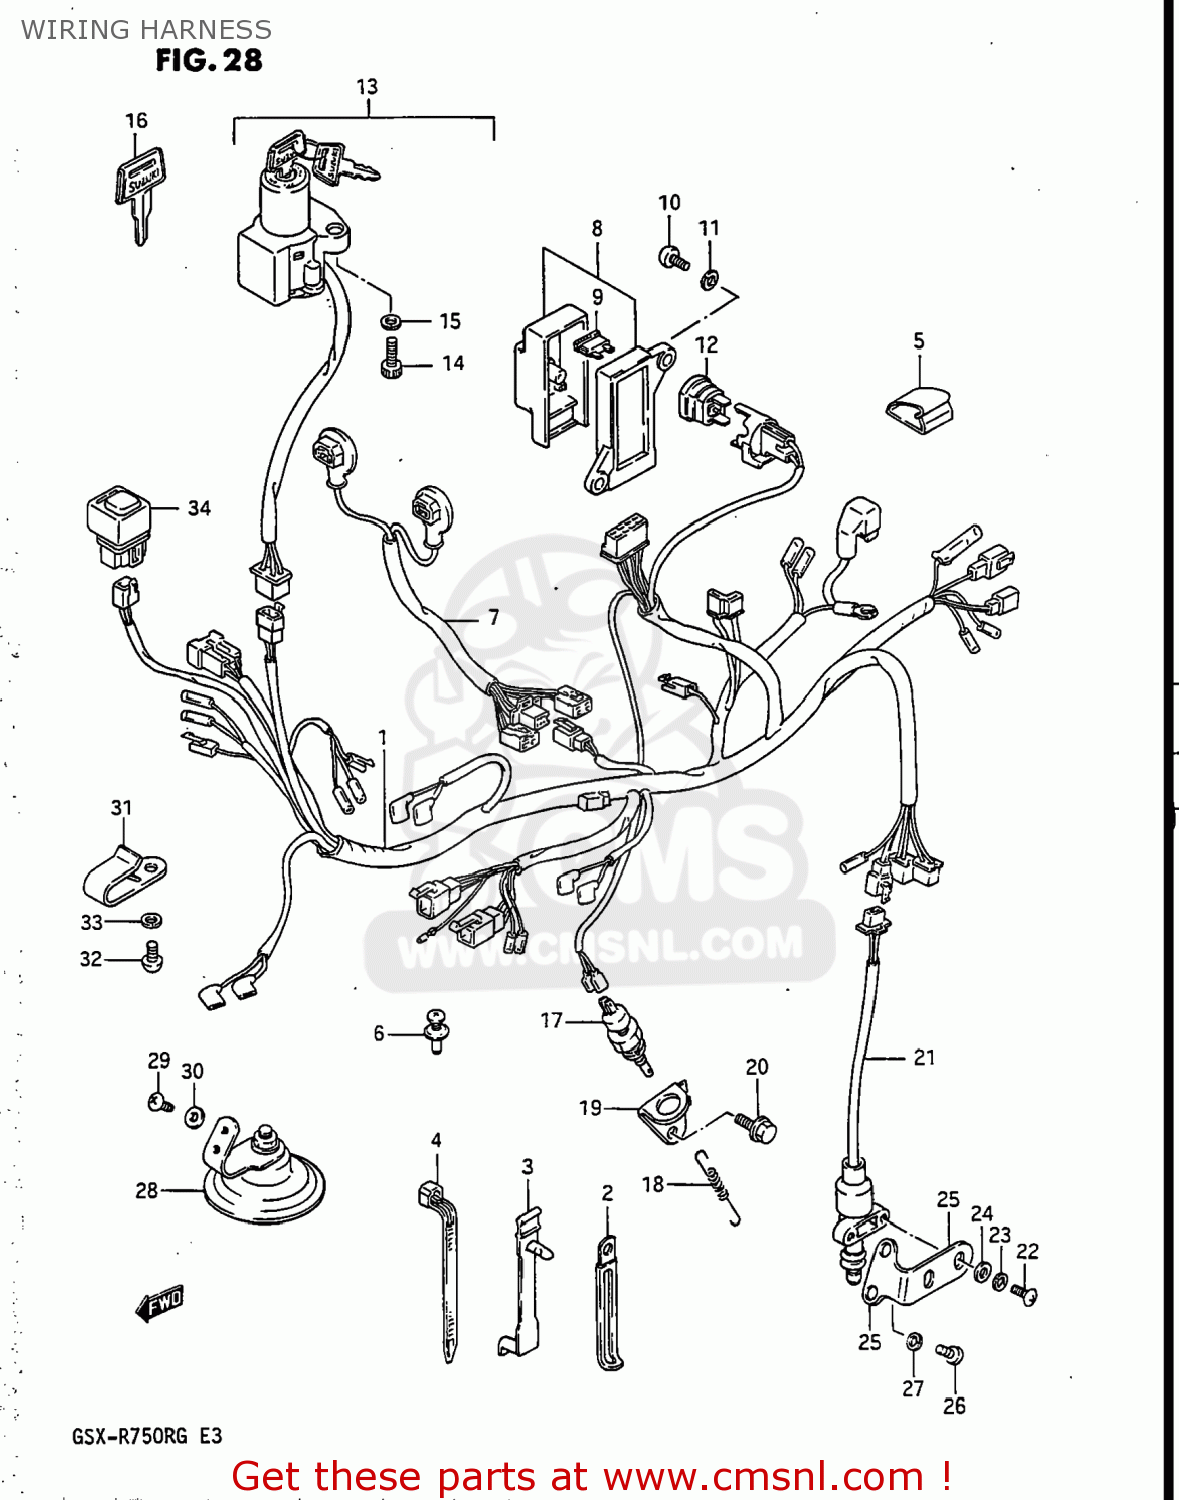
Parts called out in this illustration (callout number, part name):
1	HARNESS,WIRING
2	CLAMP
3	CLAMP(L:55)
4	CLAMP
5	CLIP
6	CLIP
7	WIRE
8	BOX ASSEMBLY,FUSE
9	FUSE(10A)
10	SCREW 6X12
11	WASHER
12	BREAKER ASSY,CIRCUT
13	SWITCH ASSY,IGNITION
14	BOLT
15	WASHER,LOCK
16	KEY,BLANK
17	SWITCH ASSY,STOP LAMP
18	SPRING
19	BRACKET,STOP LAMP SWITCH
20	BOLT (6X20)
21	SWITCH ASSY,SIDE STAND WARN
22	SCREW 5X20
23	WASHER,LOCK
24	WASHER,5MM
25	BRACKET,PROP STAND WARNING
26	SCREW 6X12
27	WASHER,LOCK
28	HORN ASSEMBLY
29	SCREW
30	WASHER,5MM
31	CLAMP,HANDLE SWITCH LEVER
32	SCREW
33	WASHER,LOCK
34	RELAY, ANTINOSE DIVE FORK
